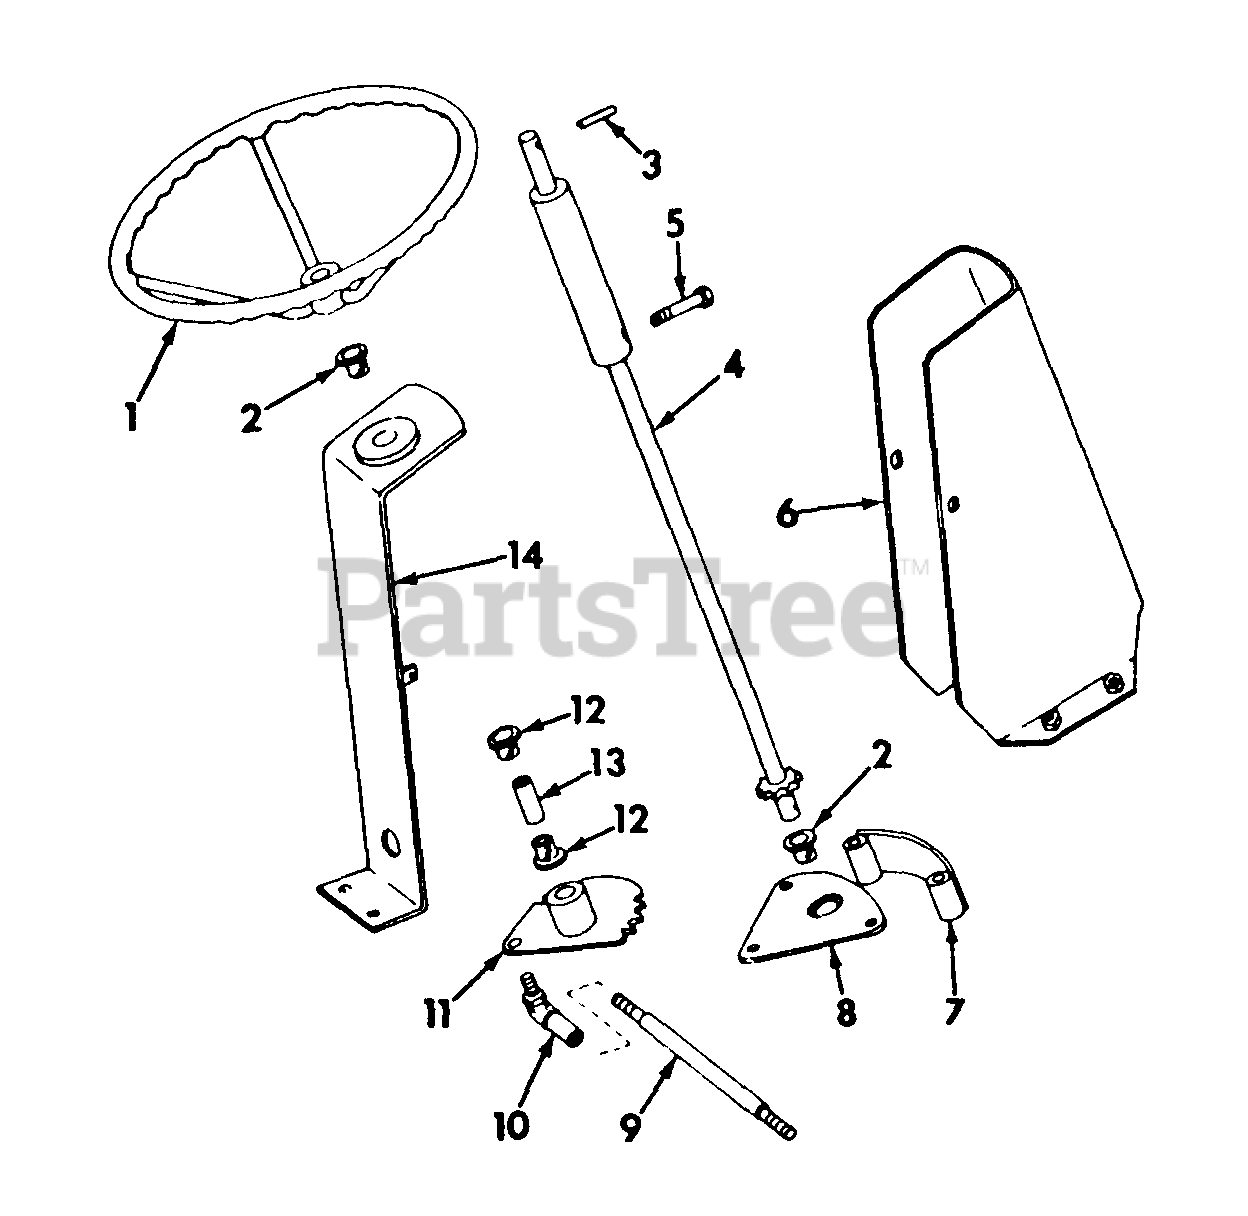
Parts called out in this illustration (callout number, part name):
1	WHEEL, STEERING
2	BEARING, STEERING SHAFT
3	PIN, 1/4 X 1-3/8 COILED SPRING
4	SHAFT ASSY, STEERING
5	BOLT, STEERING SHAFT
6	SHROUD ASSY, STEERING SUPPORT
7	COVER ASSY, FRONT STEERING GEAR
8	COVER ASSY, STEERING GEAR
9	STUD, DRAG LINK ROD
10	JOINT, TIE ROD
11	GEAR ASSY, STEERING DRAG LINK
12	BEARING, STEERING GEAR
13	BUSHING, STEERING GEAR DRAG LINK
14	SUPPORT ASSY, STEERING
